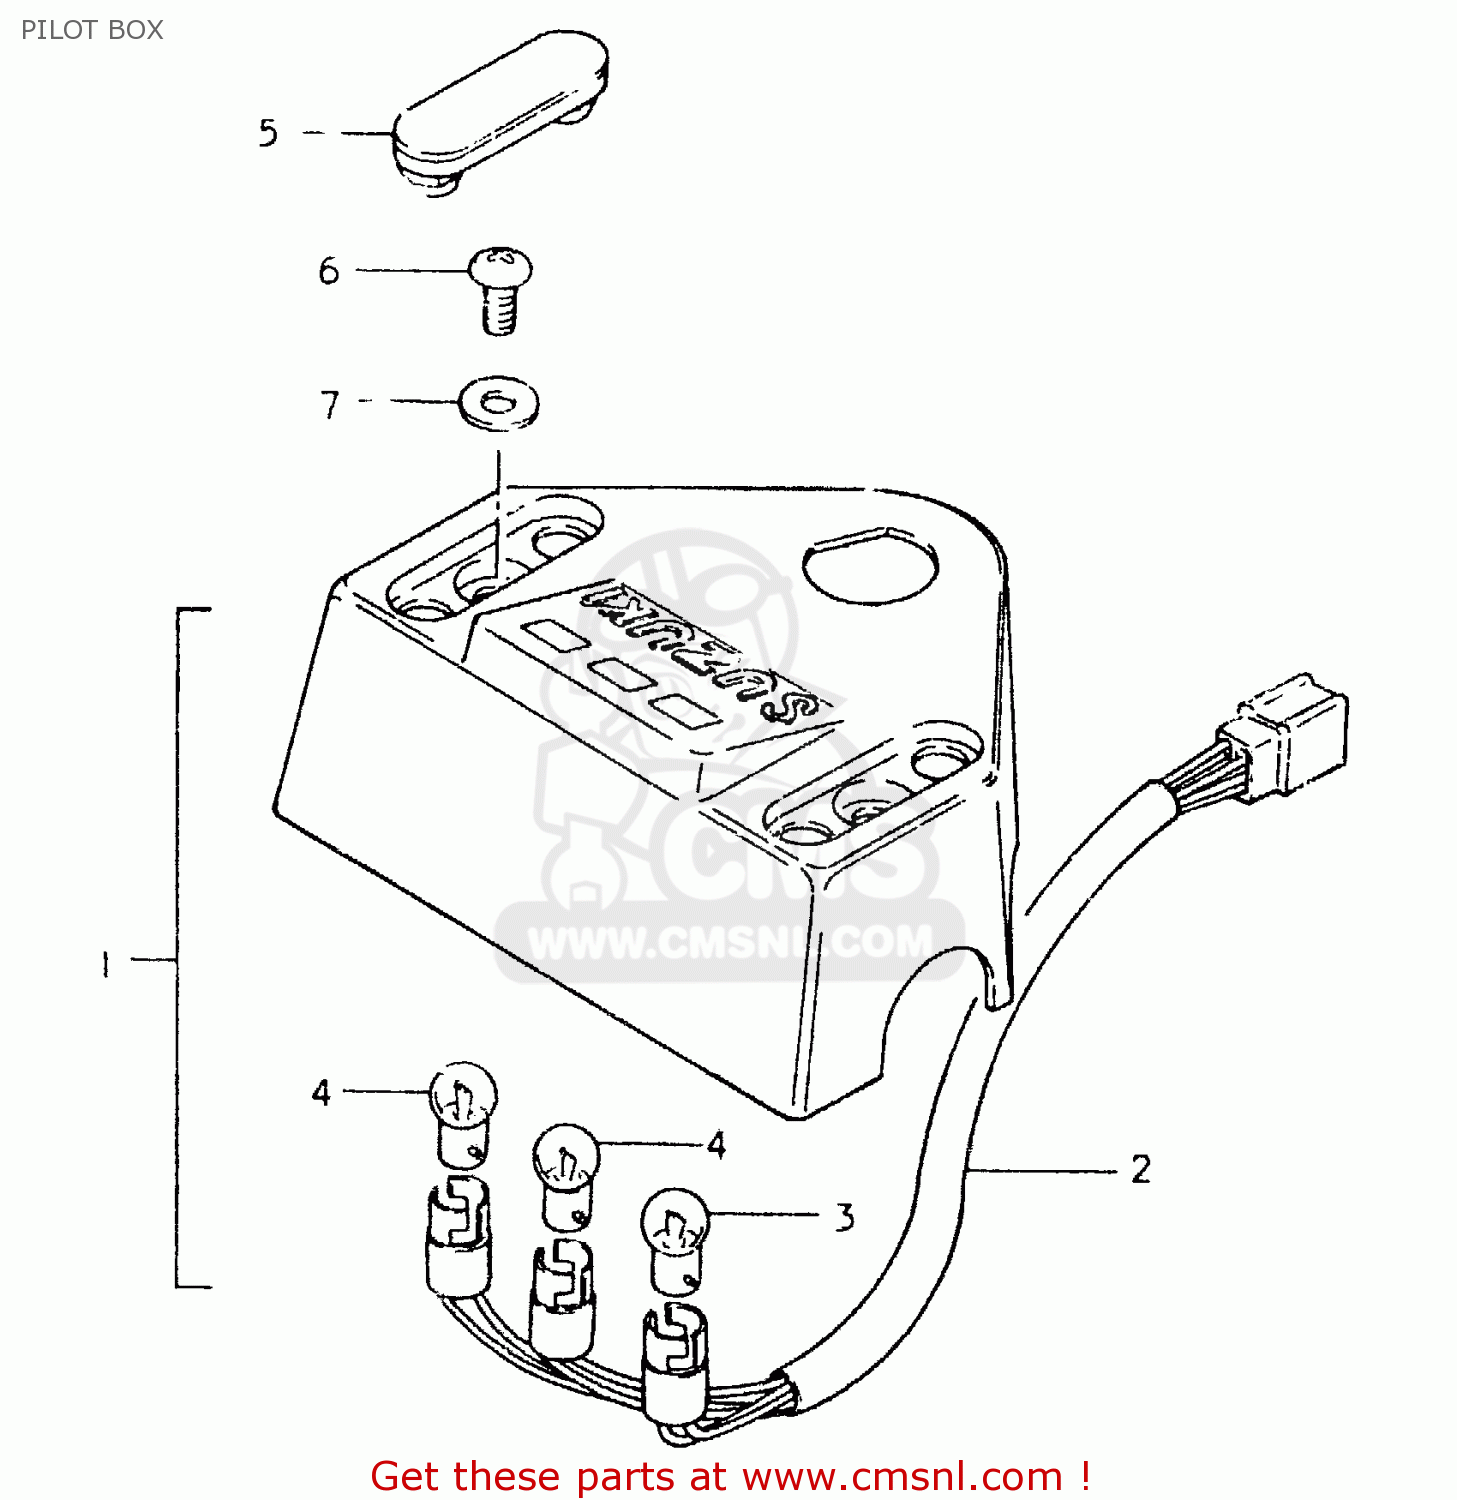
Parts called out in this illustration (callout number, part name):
1	CASE,PILOT BULB
2	SOCKET
3	BULB(6V1.7W,STANLEY,A61A)
4	BULB(6V/3W)
5	CAP,PILOT BOX BOLT
6	SCREW 6X12
7	WASHER
